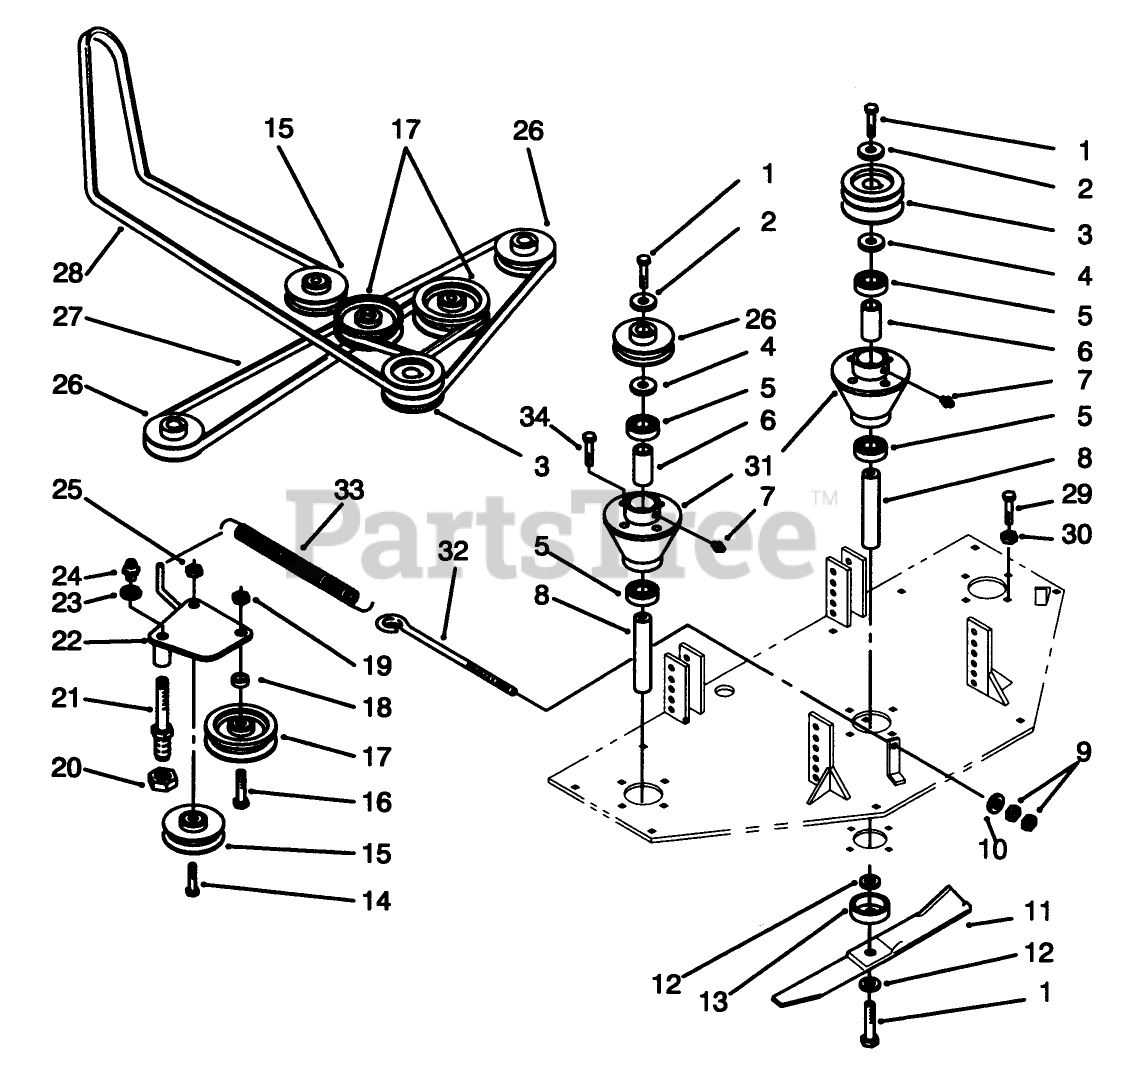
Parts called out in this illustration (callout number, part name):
1	SCREW-HH
2	WASHER-SPECIAL
3	PULLEY-CENTER
4	SPACER
5	BEARING-BALL
7	FITTING-GREASE
8	SHAFT-SPINDLE
9	NUT-HEX
10	WASHER-PLAIN
11	MOWER BLADE 17"
12	WASHER-SPECIAL
13	CUP-SPINDLE
14	SCREW-HH
15	PULLEY-IDLER
16	SCREW-HH
17	PULLEY FLAT B
18	SPACER
19	NUT-LOCK, NI
20	NUT-LOCK, NI
21	SHAFT-BELT TEN PI
22	WLDMT-IDLER PLATE R
23	RETAINING RING
24	FITTING-GREASE, 90 DEG
25	NUT-LOCK, NI
26	PULLEY-OUTER
27	BELT-V
28	BELT-50" MOW DR 724Z
29	SCREW-HH
30	NUT-JAM
31	HOUSING-SPINDLE
32	EYE-BOLT
33	Spring-Idler
34	SCREW-HH, LOCK
